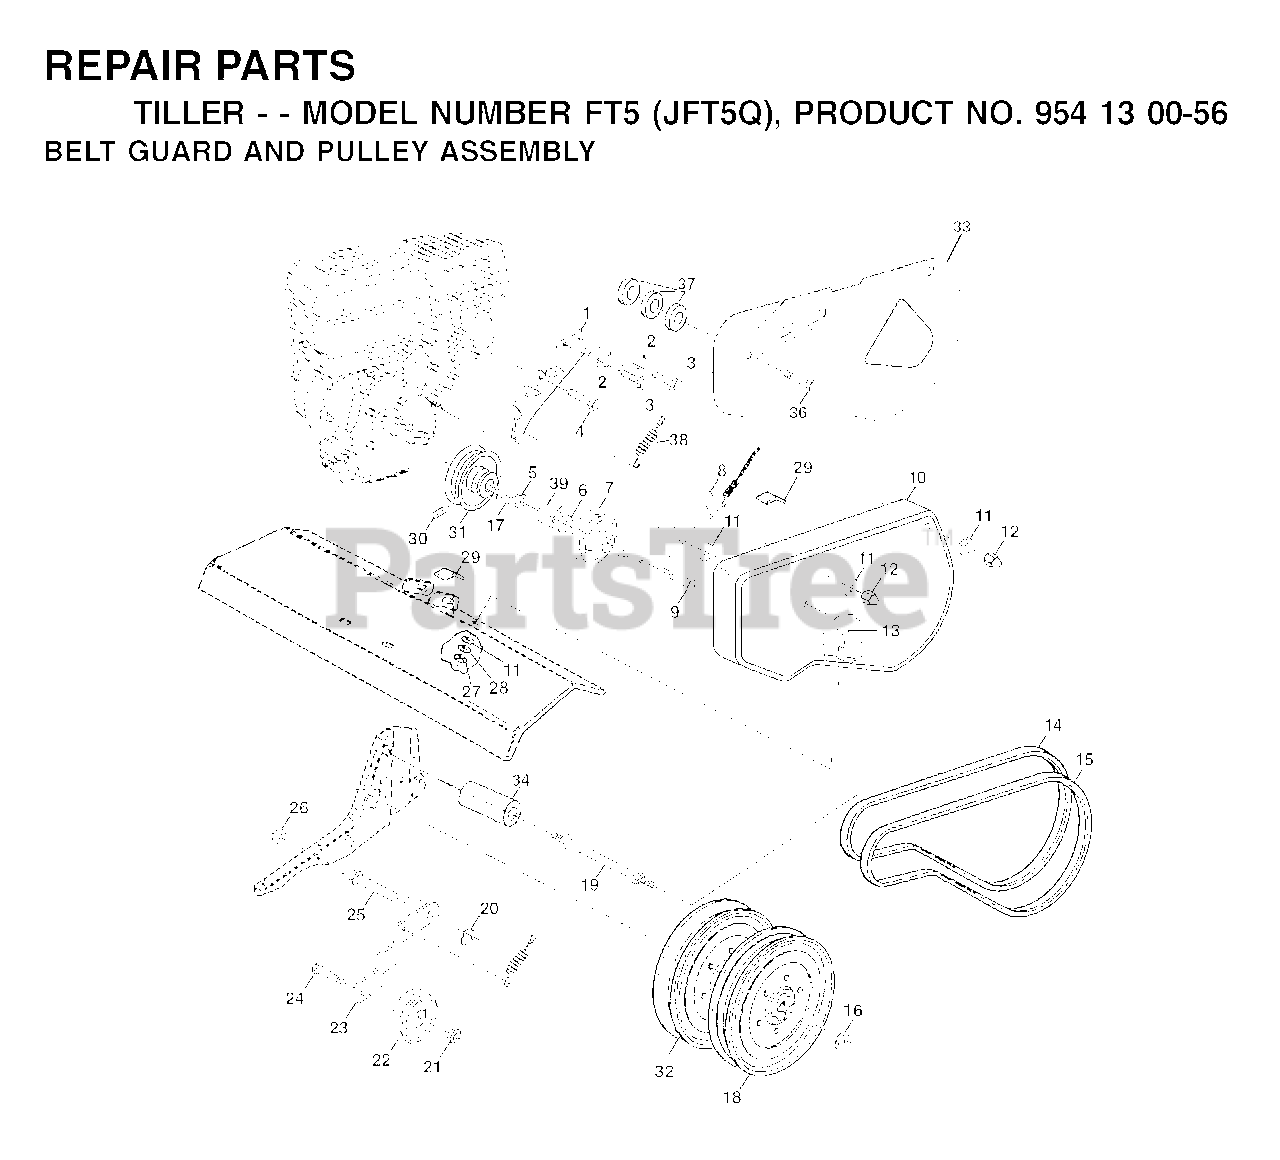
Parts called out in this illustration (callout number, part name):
1	RP BRKT.ASM.GUARD.BELT
2	CONDUIT CLIP T
3	TAPPING SCREW
7	PULLEY
8	ARM
9	BOLT
11	WASHER
12	CAP
15	BELT
16	RETAINING RING LT
18	SHEAVE,TRANS."D"
20	RING, KLIP
21	NUT
22	PULLEY, IDLER
23	ARM, IDLER
25	SHAFT.IDLER.TILLER
26	JAM NUT TI
27	NUT
28	LOCKWASHER
29	PAD IDLER TI
32	SHEAVE.TRANS
37	WASHER
38	SPRING.EXTENSION
